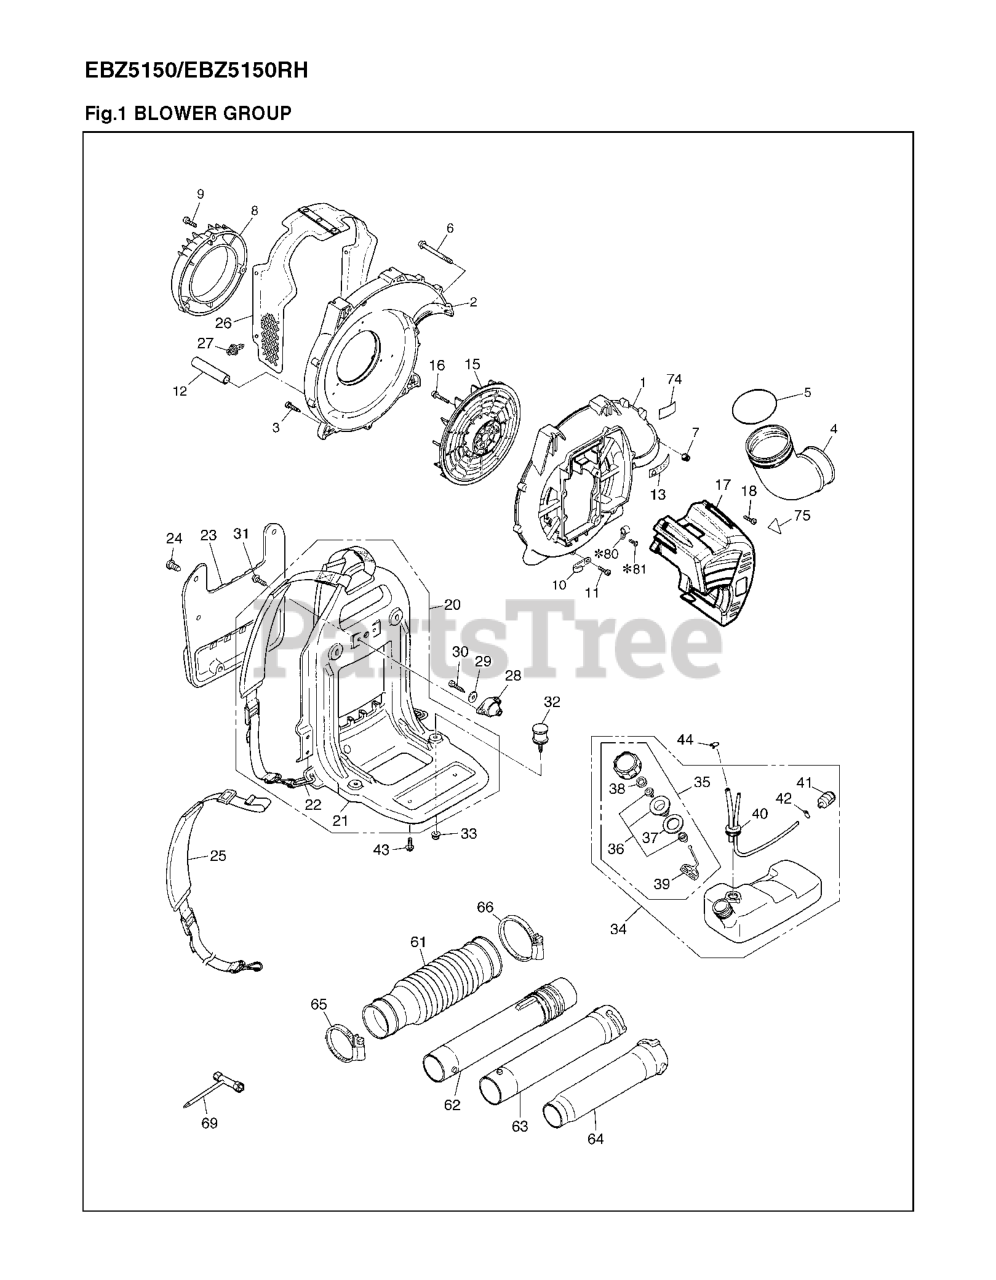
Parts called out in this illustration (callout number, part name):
1	VOLUTE CASE
2	VOLUTE COVER
4	PIPE BEND
12	TUBE
13	LABEL,CAUTION
16	BOLT
17	ENGINE COVER
20	FRAME ASSY(RPLS -3500,-3501)
21	FRAME COMP.
22	RING
24	CLIP
25	BAND ASSY. (BUCKLE 275632910)
26	NET COMP (RPLS-T402325430)
27	CLIP
28	DAMPER UPPER
29	WASHER
30	SCREW (RPLS T497054010)
32	DAMPER
34	TANK ASSY
35	ASSY FUEL CAP
36	HOLDER-A
40	PIPE COMPLETE
41	FILTER ASSY
42	CLIP
44	CLIP
61	BELLOWS
62	SWIVEL JOINT
63	PIPE STRAIGHT
64	PIPE,END
66	CLAMP(F115)
69	SOCKET
80	CLAMP
81	SCREW
